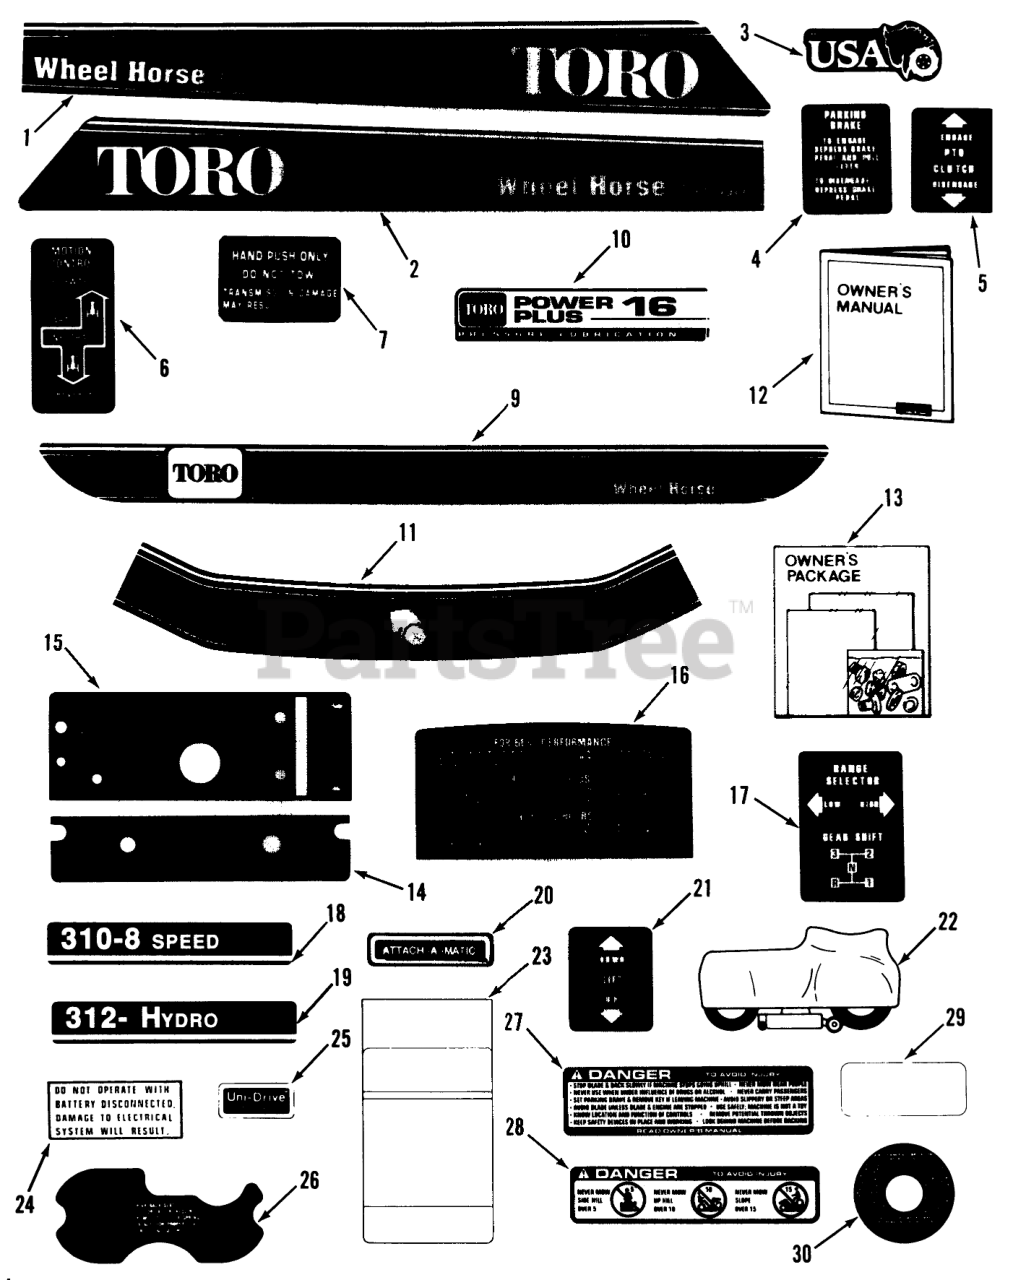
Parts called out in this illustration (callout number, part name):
1	DECAL-HOOD CLASSIC
4	DECAL-PARKING, BRAKE
5	DECAL PTO CLUTCH
6	DECAL-MOTION CONTROL
7	DECAL-DO NOT TOW
9	DECAL-FENDER
10	DECAL-PWR PLUS 16 PL
12	Operator-s Manual-Tractor 310-8, 312-8, 416-8
17	DECAL-SHIFT PATTERN
21	DECAL-LIFT
23	MAINTENANCE-DECAL
29	DECAL-OVERLAY
30	KOHLER 41-113-02
